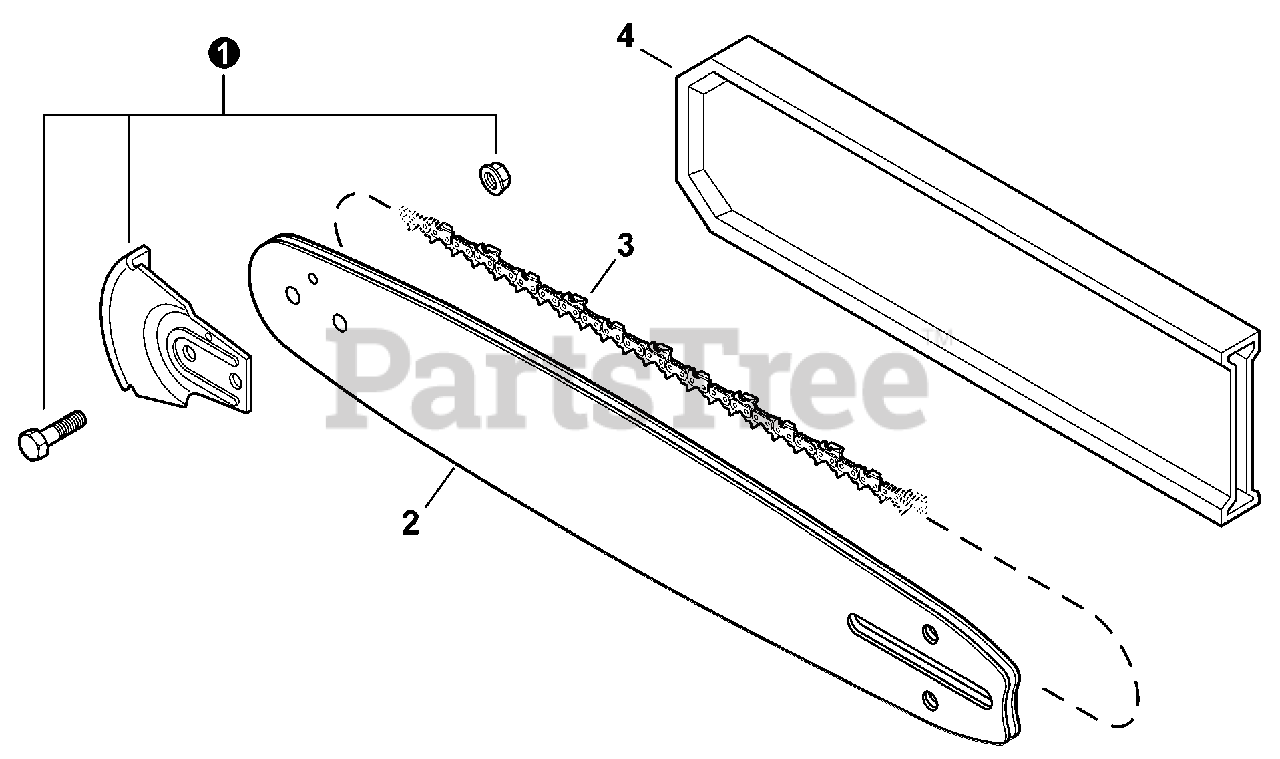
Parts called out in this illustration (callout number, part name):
1	KICK GUARD KIT
2	GUIDE BAR, 12"
2	GUIDE BAR, 12" MICRO-LITE PRO
2	GUIDE BAR, 14"
2	GUIDE BAR, 14" MICRO-LITE PRO
3	SAW CHAIN 12"
3	SAW CHAIN 12" - MICRO-LITE
3	SAW CHAIN 14"
3	SAW CHAIN 14" - MICRO-LITE
4	SCABBARD 12"
4	SCABBARD 14"
